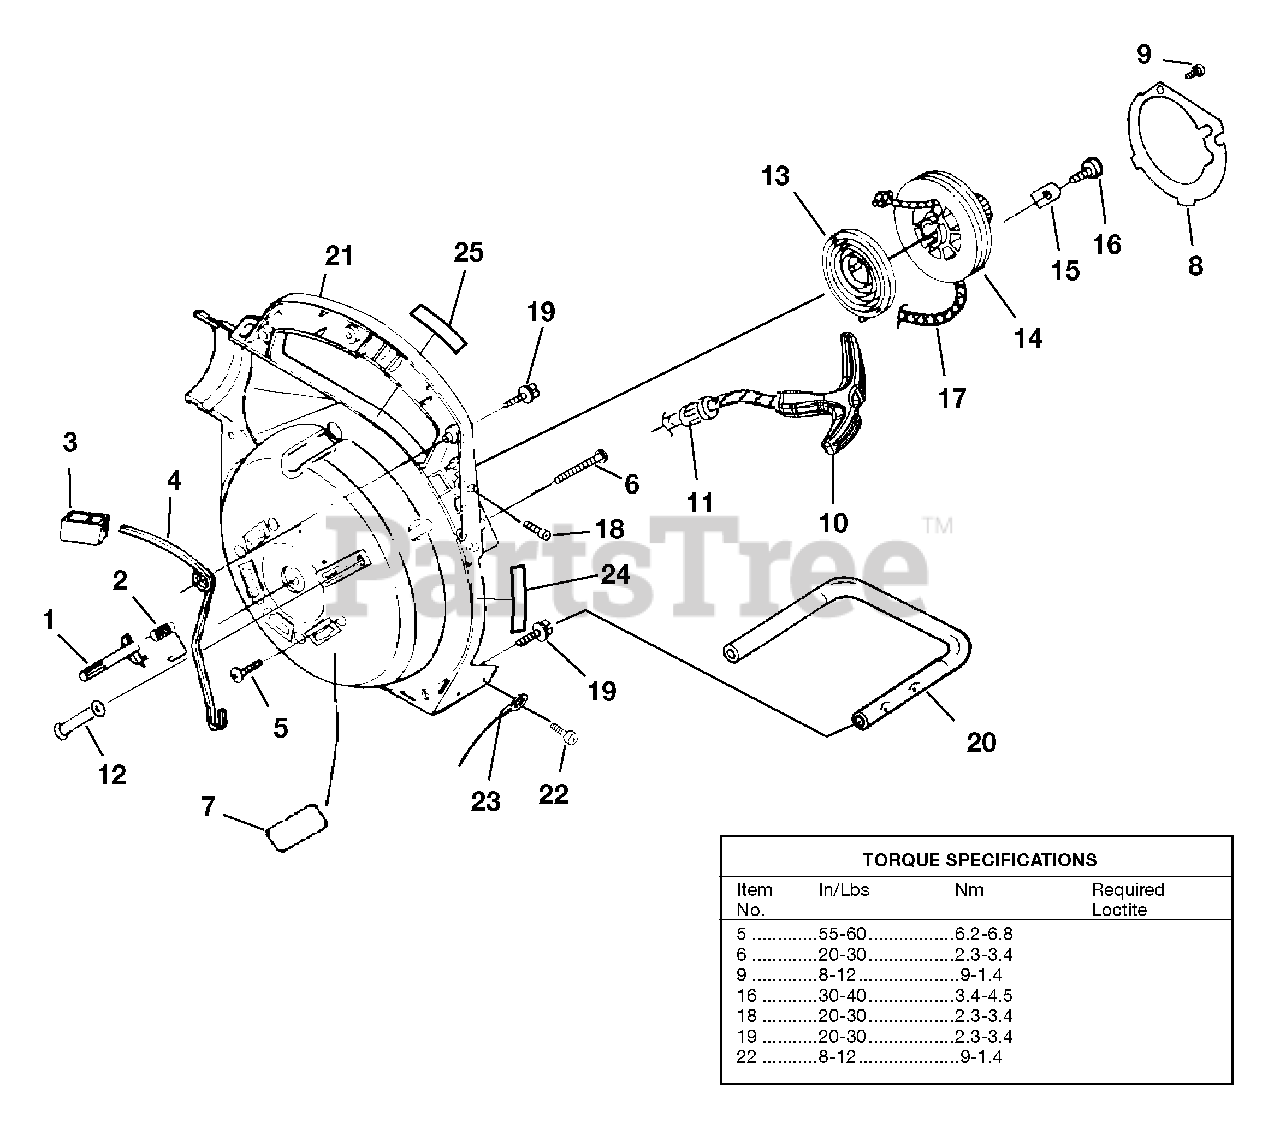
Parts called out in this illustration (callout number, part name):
1	LATCH-Throttle
2	SPRING-Throttle Latch
3	TRIGGER-Throttle
4	LEVER-Throttle
5	SCREW-Thread Form. (10-24 X 3/4)
6	SCREW-Thread Form. (#10 X 1 5/8)
7	HEAT SHIELD
8	PLATE-Rotor
9	SCREW-Thread Form. (#6 X 1 3/8)
10	GRIP-Starter (Yellow)
11	BUSHING-Starter
12	GUIDE-Starter Rope
13	SPRING & CONTAINER
14	PULLEY-Starter
15	BRACKET-Retaining
16	SCREW-Thread Form. (#10 X 1/2)
17	ROPE-Starter
18	SCREW-Phil. Hd. (8-32 X 5/8)
19	SCREW-Thread Form. (10-24 X 3/4)
21	INNER VOLUTE HOUSING
23	LEAD-Ground
24	DECAL-Help
25	LABEL-Decible Level 67 d B (A)
